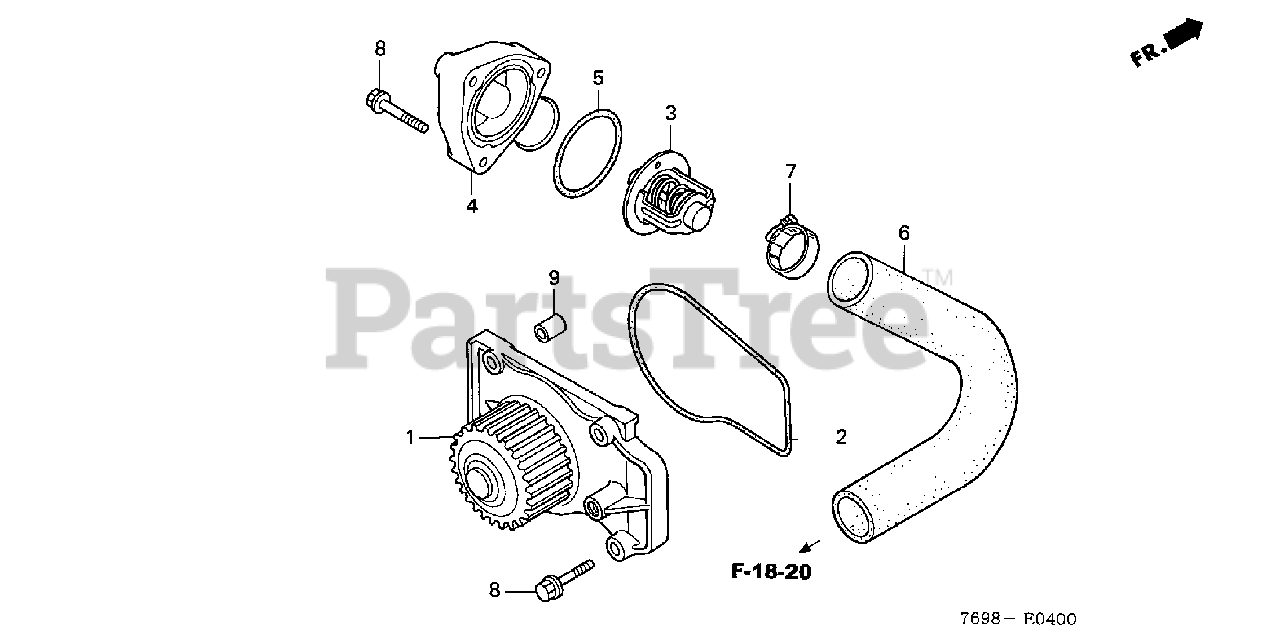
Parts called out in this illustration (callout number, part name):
1	WATER PUMP
2	O-RING, WATER PUMP
3	THERMOSTAT
4	COVER, THERMOSTAT
5	O-RING, THERMOSTAT COVER
6	HOSE B, WATER (LOWER)
7	BAND, WATER HOSE
8	BOLT, FLANGE (6X32)
9	PIN A, DOWEL (8X14)
